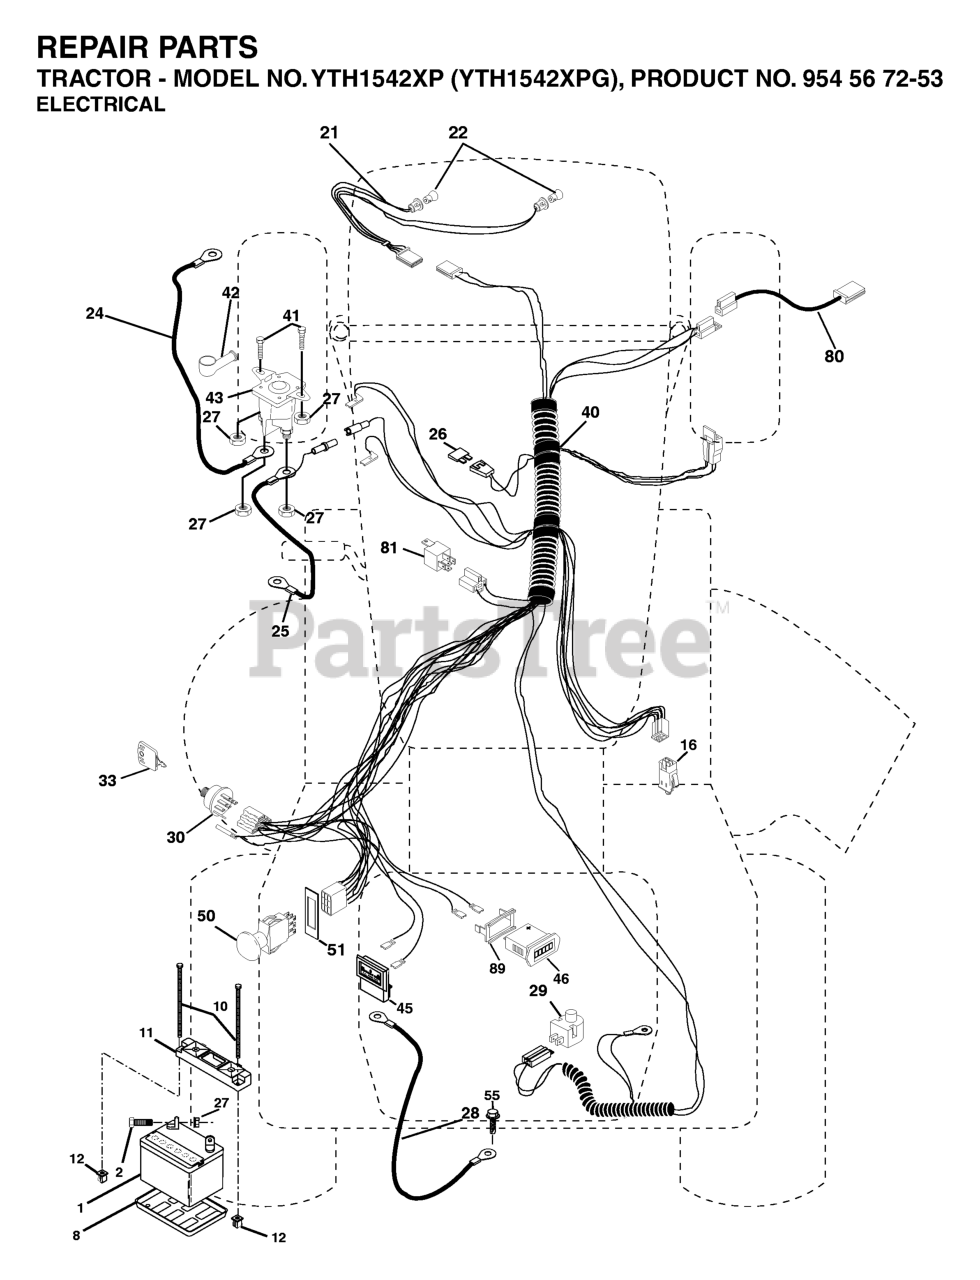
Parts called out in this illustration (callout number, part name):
1	BATTERY 12V .35 AMP
2	BOLT.HEX.1/4.X.3/4.DICHROMATE
8	BATTERY TRAY T
10	BOLT 1/4-20 X 7.5
11	BATTERY HOLDDOWN FRONT MOUNT
12	NUT, PUSH NYLON 1/4" BATTERY
16	SWITCH INTERLOOK PUSH-IN
21	HARNESS.W/LIGHT SOCKET
24	CABLE BATTERY 6 GA 22" W/16W
25	BATTERY CABLE GT
26	FUSE 20AMP
27	NUT
28	CABLE GROUND 6 GA 21" 90T BLK
29	PLUNGER SWITCH (COLOR:OLIVE)
30	IGNITION SWITCH
33	KEY MLD GEN DELTA
40	HARNESS IGN.
41	BOLT
42	TERMINAL COVER
43	SOLENOID
46	HOUR METER
50	RP.PTO.SWITCH.8 TERMINAL.BLACK
51	FRAME RETAINING RING
55	Screw 5/16-18 x 1/2 Hex, Self Tapping 5/16-18 x 1/2
80	HARNESS, CLUTCH
81	RELAY.ASSY.T
89	BRACKET SNAP-IN HOURMETER
